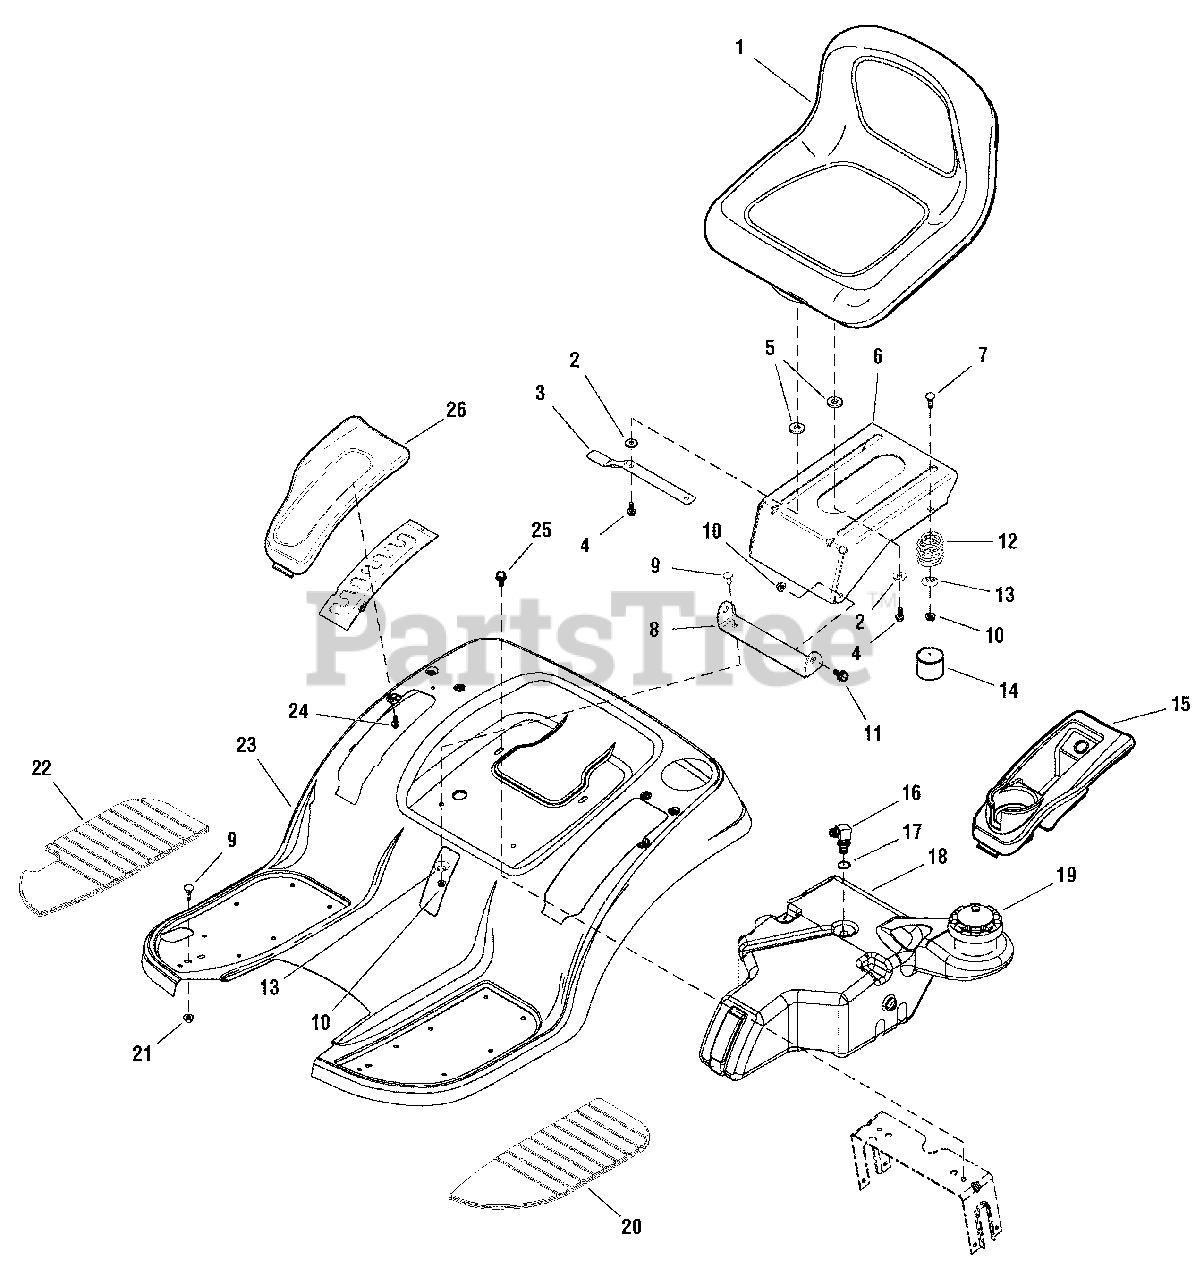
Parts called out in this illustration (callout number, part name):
1	SEAT, Hi Back, Steel Pan
2	WASHER, Plain, 5/16
3	LATCH, Seat 20GA E-Coat
4	CAPSCREW, Hex Head Flange Dog Point, 5/16-18 x 1
5	SPACER, 0.32 ID x 1-1/2 OD x 3/10 THK Powdered Metal Yellow
6	SUPPORT, Seat 12GA
7	CARRIAGE BOLT, 5/16-18 x 3/4
8	PIVOT, Seat 10GA
9	BOLT, Carriage, 5/16-18 x 3/4
10	NUT, Hex Flange, 5/16-18 ESNA
11	BOLT, Shoulder, 5/16-18 x 15/32
12	SPRING, Compression
13	WASHER, Spring, 5/16 x 1 1/4
14	COVER, Spring
15	POD, LH Cup Holder
16	ELBOW FITTING
18	TANK, Fuel
19	CAP, Gas
20	PAD, Footrest LH
21	NUT, Hex, Flange Whizlock, 5/16-18
22	PAD, Footrest RH
23	DECK, Seat w/Footrests (Red)
24	SCREW, Hex, Washer Head, Plastite, 1/4-20 x 1/2
25	SCREW, Taptite, 5/16-18 x 5/8
26	POD, RH Lift Quadrant
